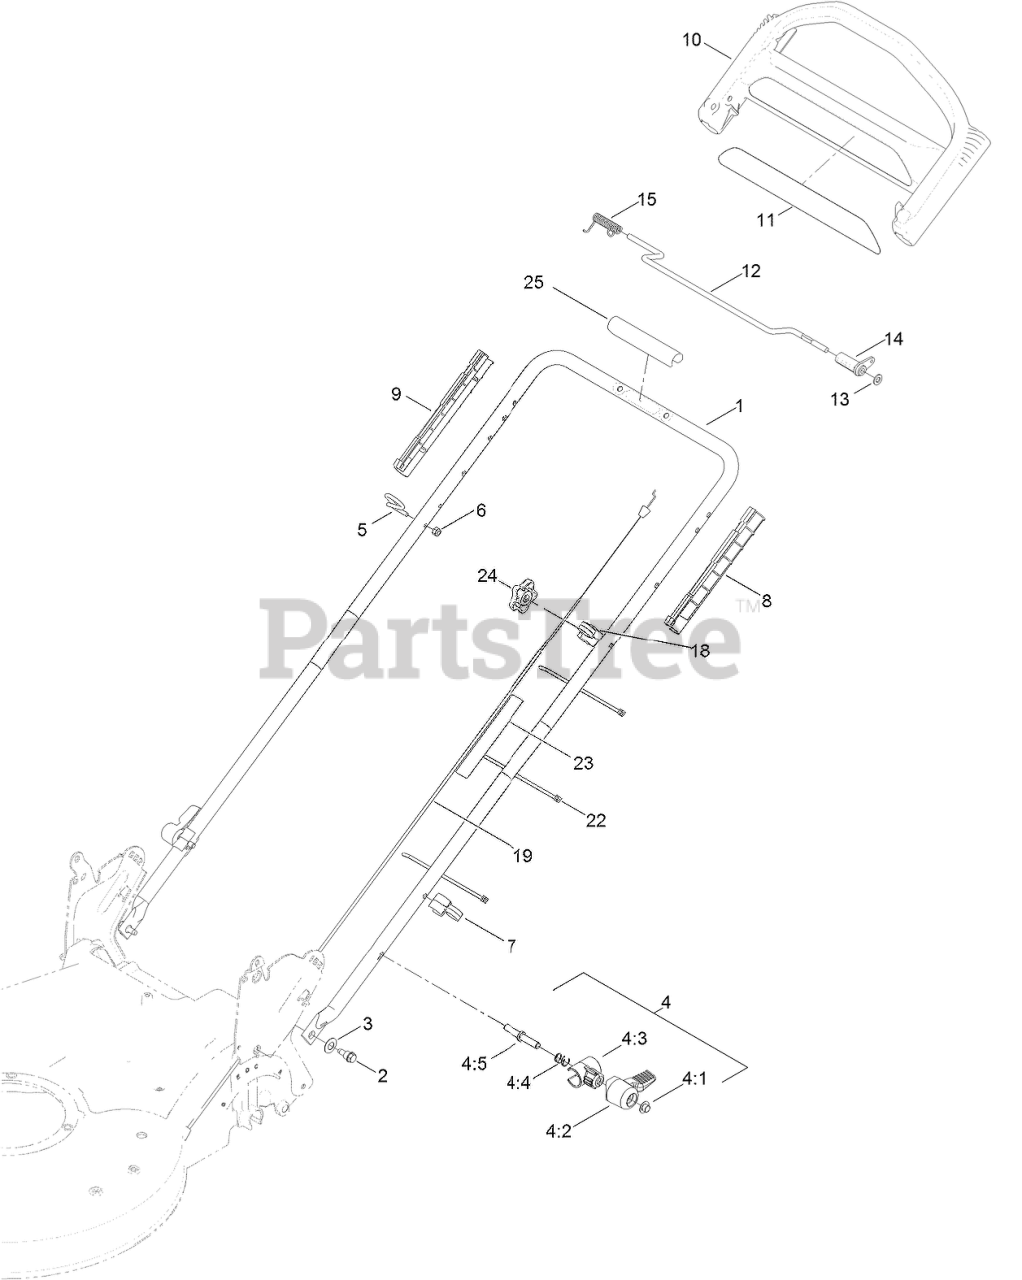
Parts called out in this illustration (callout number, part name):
2	BOLT-SHOULDER
3	WASHER-SPRING, CONICAL
4	QUICK RELEASE ASM
4:1	NUT-PUSH
4:2	LEVER
4:3	ANCHOR-SPRING
4:4	SPRING-COMPRESSION
4:5	ROD-RELEASE
5	GUIDE-ROPE
6	NUT-LOCK, NI
7	GUIDE-CABLE
8	GUIDE-LH
9	GUIDE-RH
10	HANDLE-CONTROL
12	BAR-CONTROL, TRACTION
13	WASHER-PLAIN
14	LEVER-TRACTION
15	Spring-Torsion
18	ANCHOR-CABLE
19	CABLE-TRACTION
22	TIE-CABLE
23	DECAL-TRACTION, ADJUST
24	KNOB-HANDLE, LOCKING
25	HANDLE-COVER
